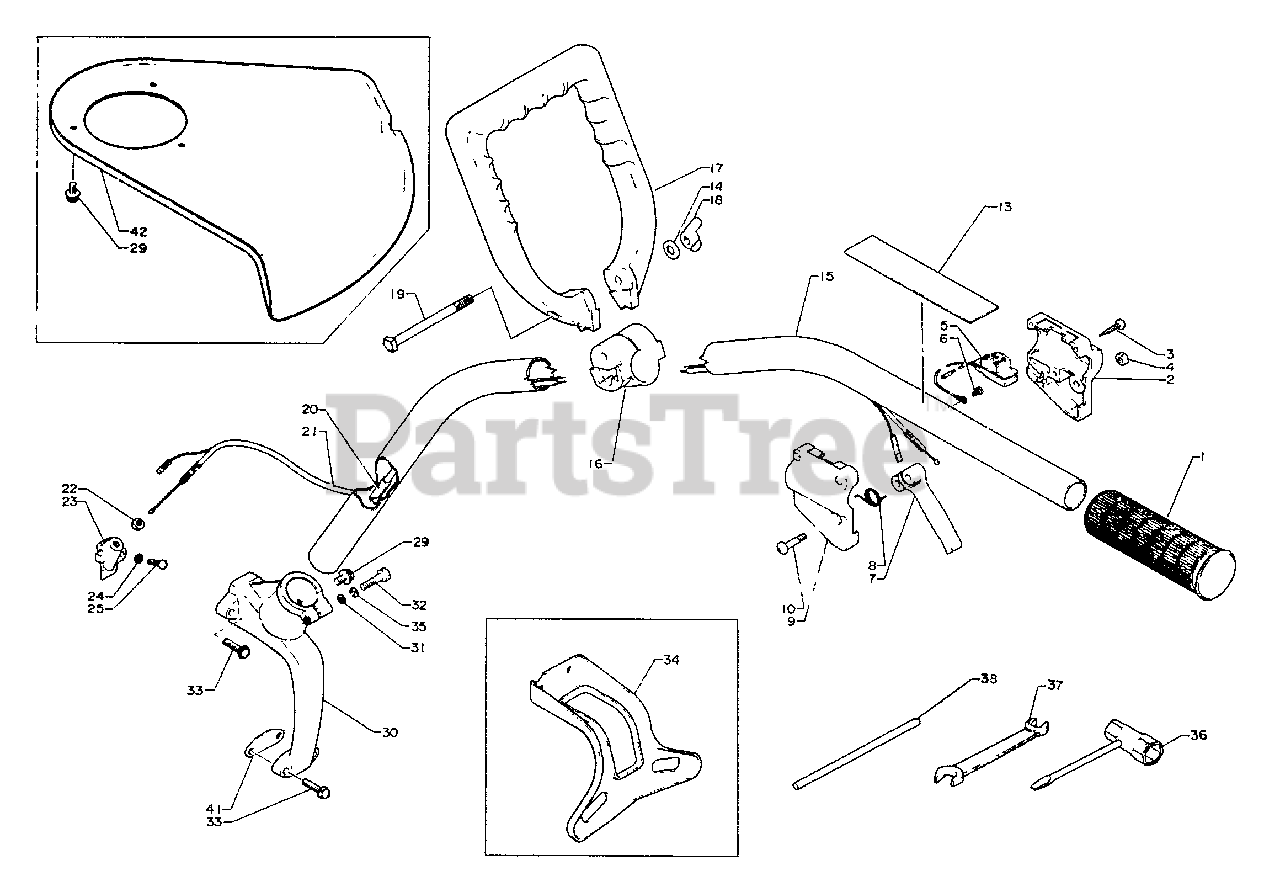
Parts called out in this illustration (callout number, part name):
1	GRIP
2	BRACKET, TRIGGER
3	SCREW 4×25
4	LOCKNUT - 5
5	IGNITION SWITCH ASSY
6	SCREW - 4×8
7	TRIGGER, THROTTLE
8	SPRING, THROTTLE
9	BRACKET, THROTTLE CONTROL - LEFT
13	LABEL
15	PIPE, MAIN
16	BRACKET, HANDLE
18	NUT - 6 -- BUTTERFLY
19	BOLT
20	COVER, THROTTLE CABLE
21	CABLE, THROTTLE
23	HOLDER, CABLE
24	WASHER 4 MM
25	SCREW 4×12
29	SCREW 5×10
30	BRACKET
31	WASHER, FLAT 5.5×10×0.8
32	BOLT - 5×25
33	SCREW 5×20
34	STAND
35	WASHER, SPRING 5
36	T-WRENCH
37	SPANNER 8×10
38	TOOL, LOCKING 5×120 MM
41	SPACER
42	COVER
